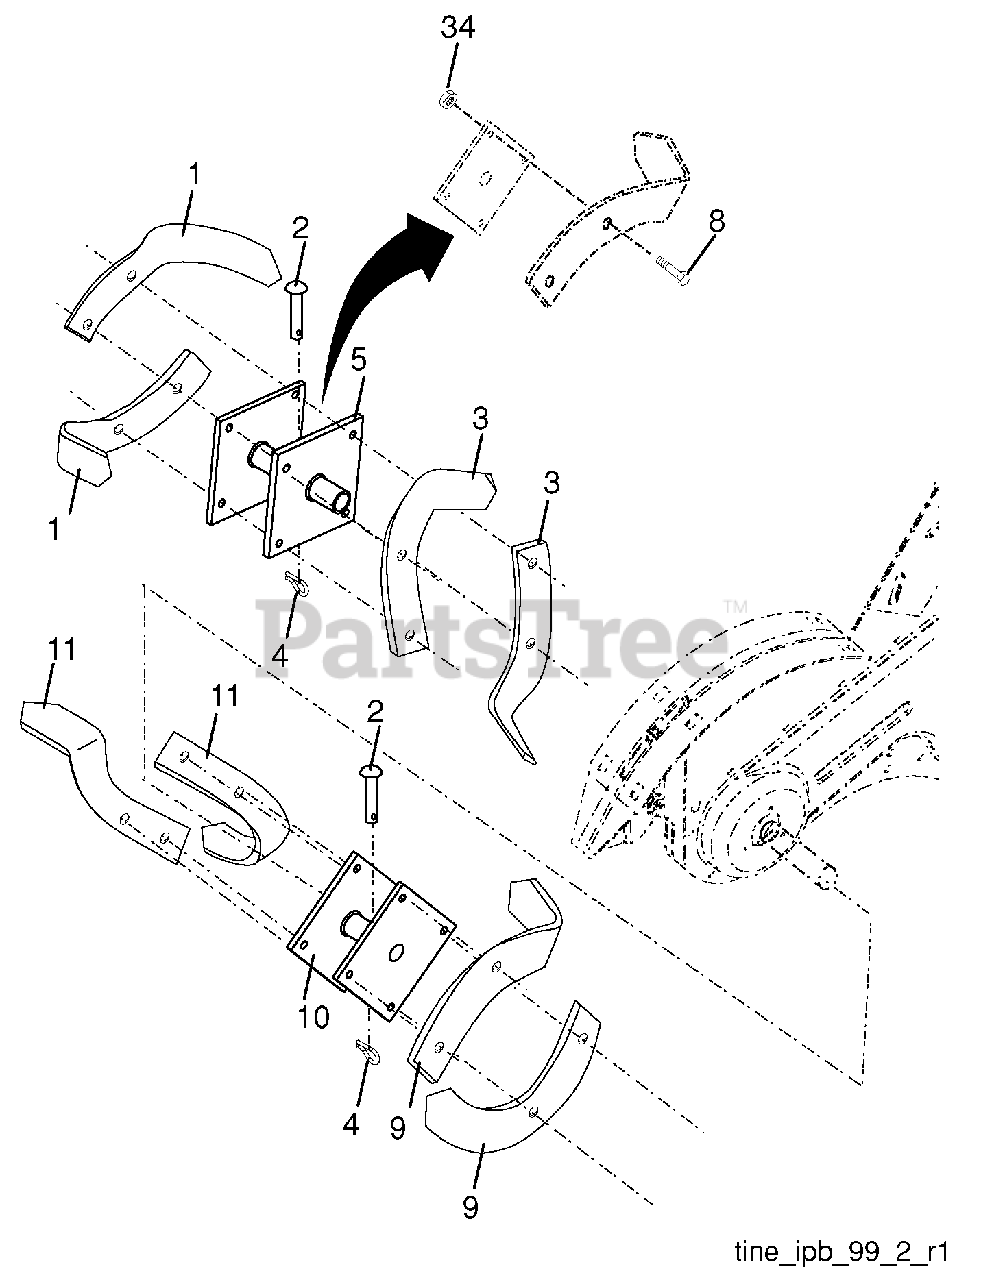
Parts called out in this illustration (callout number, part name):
1	Tine, Outer, L.H.
2	Clevis Pin
3	Tine, Inner, L.H.
4	Retainer, Spring Zinc
5	Assembly, Hub and Plate, L.H.
8	Bolt, Hex 3/8-24 x 1
9	Tine, Outer, R.H.
10	Assembly, Hub and Plate, R.H.
11	Tine, Inner, R.H.
34	Nut Crownlock 3/8-24
